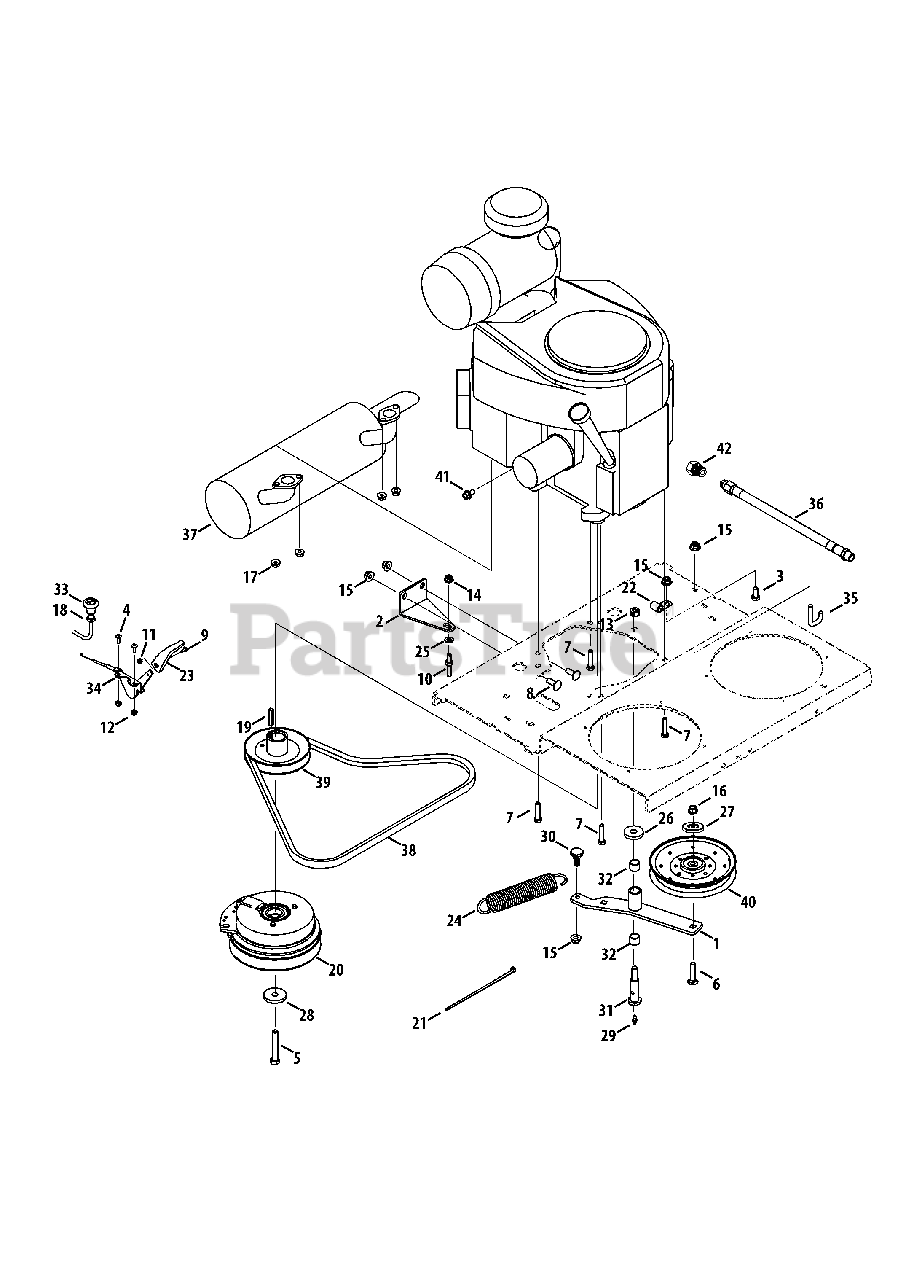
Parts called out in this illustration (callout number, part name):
1	Idler Bracket
2	Clutch Retainer Bracket
3	Hex Cap Screw, 3/8-16 x .75
4	Screw, #10-24 x .625
5	Hex Cap Screw, 7/16-20 x 2.75
6	Carriage Bolt, 3/8-16 x 1.00
7	Hex Cap Screw, 3/8-16 x 1.25
8	Carriage Bolt, 3/8-16 x 1.00
9	Screw, #8-32 x .375
10	Stud, Pivot Ball Joint
11	Nut, #8-32, Hex
12	Nut, #10-24, Hexlock
13	Nut, 7/16-14, Hexlock
14	Nut, 5/16-18, Flangelock
15	Nut, 3/8-16, Flangelock
16	Nut, 3/8-16, Flangelock
17	Nut, M8-1.25, Hexlock
18	Jam Nut, 3/8-24
19	Key, 1/4 x 1.50
20	Electric PTO Clutch
21	Cable Tie
22	Clip, .407 x 1.80
23	Throttle Control Knob
24	Extension Spring, 1.5 x 7.5
25	Washer, .344 x .688 x .065
26	Washer, .471 x 1.50 x .225
27	Pulley Cap
28	Washer, .471 x 1.50 x .225
29	Grease Fitting
30	Shoulder Screw, .625 x .302, 3/8-16
31	Shoulder Bolt, .625 x 1.947, 7/16-14
32	bearing, .638 x .753 x .615
33	Choke Control Cable
34	Throttle Cable
35	Transmission Spring Hook
36	Oil Drain Hose
37	Muffler
39	Drive Pulley
40	Idler Pulley
41	Hex Cap Screw, M8 x 1.25 x 16MM
42	Hex Fitting, 1.0
